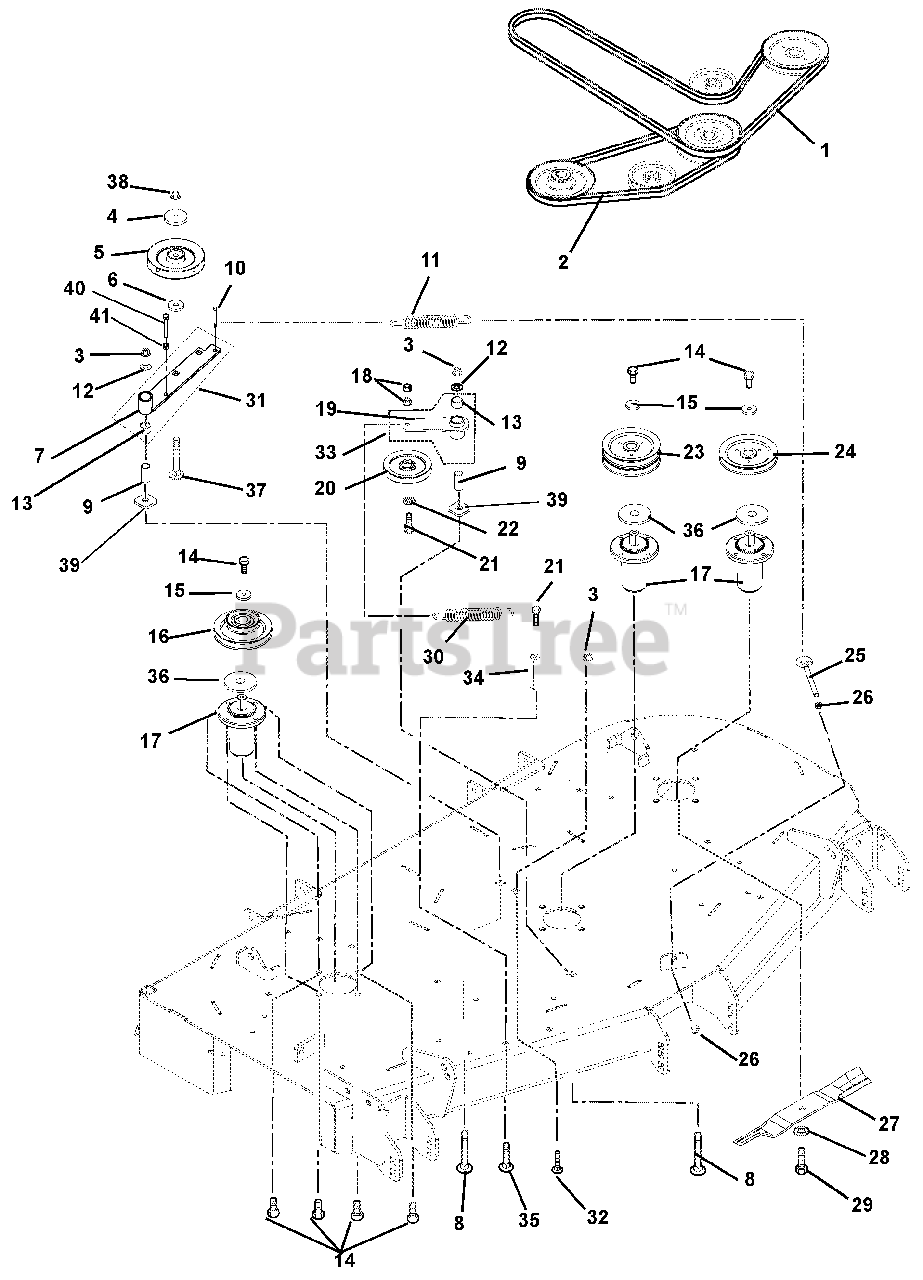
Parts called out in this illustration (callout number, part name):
1	HEX BELT, BB-WRAPPED
2	V-BELT, B-COGGED
3	@NUT-LK-NYL-FLG .50-13 YWZC
4	CAP, IDLER BEARING SEALING
5	SHV, .50"ID X 6.00"OD V-IDLER
6	BSHG, SPCR .502X.997X.50 PM
7	WMT, IDLER ARM
8	@BLT-RDHDSQNK .50-13X3.50 G5YZ
9	BSHG, SPCR .502X.997X2.03 PM
10	BLT,SHLDR EP .38-16X.30 HEX YZ
11	SPRING, EXTENSION
12	@WSHR-FL-STL.563X1.38X.109YWZC
13	BSHG, 1.00 X 1.125 X 1.937
14	BLT-HEX .38-16X1.0 GR8 YZ EP30
15	WSHR,FLT STL.406X1.50X.245YWZC
16	PULLEY, DBL-1"IDX6.75"&4.25"OD
17	ASSEMBLY, SPINDLE
18	@NUT-LK-CTR .38-16 YWZC
19	WMT, IDLER ARM - BLACK
20	SHV, .38"ID X 5.00"OD V-IDLER
21	@BLT-HEX .38-16X2.25 GR5 YWZC
22	@WSHR-FL-STL.406X.812X.065 YWZ
23	PULLEY, DOUBLE-1"ID X 6.75"OD
24	PULLEY, V-1" ID X 6.75" OD
25	BOLT, .38-16X6.00 .62 DIA EYE
26	NUT-HEX-JAM .375-16 YWZC
27	BLADE, MOWER (20.50")
28	WSHR-BLVL .669X1.535X.138
29	BLT-HEX .62-18X1.75 GR8 YWZC
30	SPRING, EXTENSION
31	ASM, IDLER PIVOT ARM (PTO)
32	BLT-RDHDSHSQNKFT.50-13X1.50 G5
33	ASM, IDLER ARM (DECK)
34	NUT COUPLING .375-16X1.75
35	@BLT-RDHDSHSQNK.38-16X1.0 G5YZ
36	RETAINER, GREASE
37	@BLT-RDHDSQNK .50-13X3.00 G5YZ
38	@NUT-LK-NYL-FLG .50-13 YWZC
39	WSHR-FLT .640X1.75X.250
40	@BLT-HEX .38-16X2.75 GR5 YWZC
41	@NUT-HEX .38-16 YWZC
